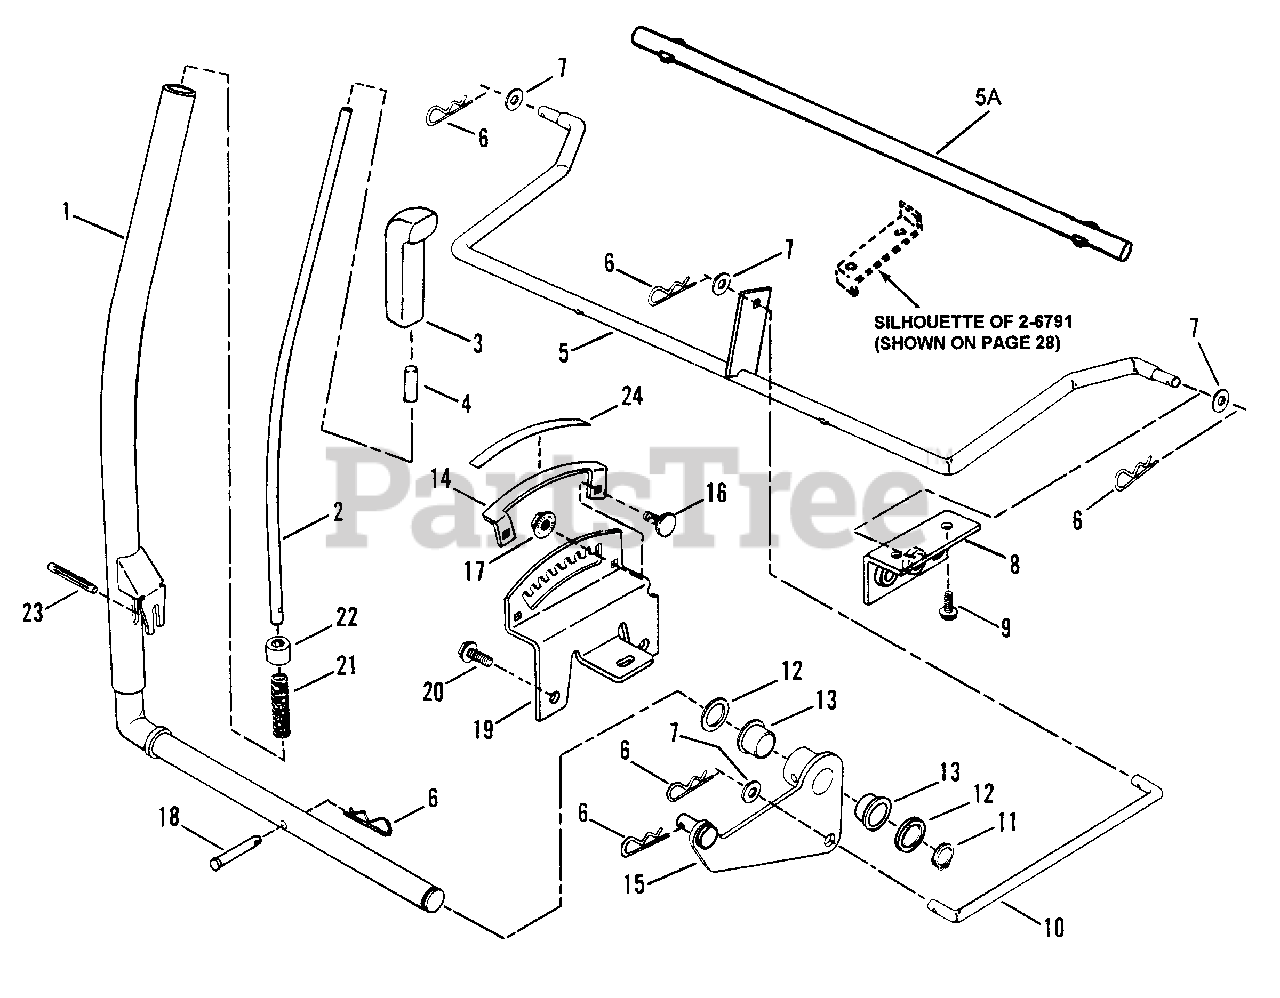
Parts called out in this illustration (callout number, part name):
1	ARM, Implement Lift Lever
2	ROD, Lift Lever
3	GRIP, Lift Lever
4	CAP, Lift Release
5	ARM, Rear Lift
5A	ROD, Uplatch (Used on ground-following decks only)
6	PIN, 3/32 x 1-1/2" Hair
7	WASHER, 3/8" Flat
8	BRACKET, Hanger
9	SCREW, 5/16-18 x 5/8" S.-Tap
10	LIFT-ROD
11	RING, Retaining EXT 7/8"
12	WASHER, Lift Lever .905 x 1.25 x .091
13	BEARING, Lift Lever
14	INDICATOR, Cut Height
15	ASSEMBLY, Lift Lever Pivot
16	BOLT, 1/4-20 x 5/8" Carriage
17	NUT, 1/4-20 Hex Flange Lock
18	PIN, Clevis, 5/16 x 1 11/16"
19	QUADRANT, Lift Lever
20	SCREW, 5/16-18 x 7/8" Self-Tapping
21	SPRING, Lift Lever
22	PLUG, Lift Lever Nylon
23	PIN, 3/16 x 2" Groove
24	DECAL, Cut Height
